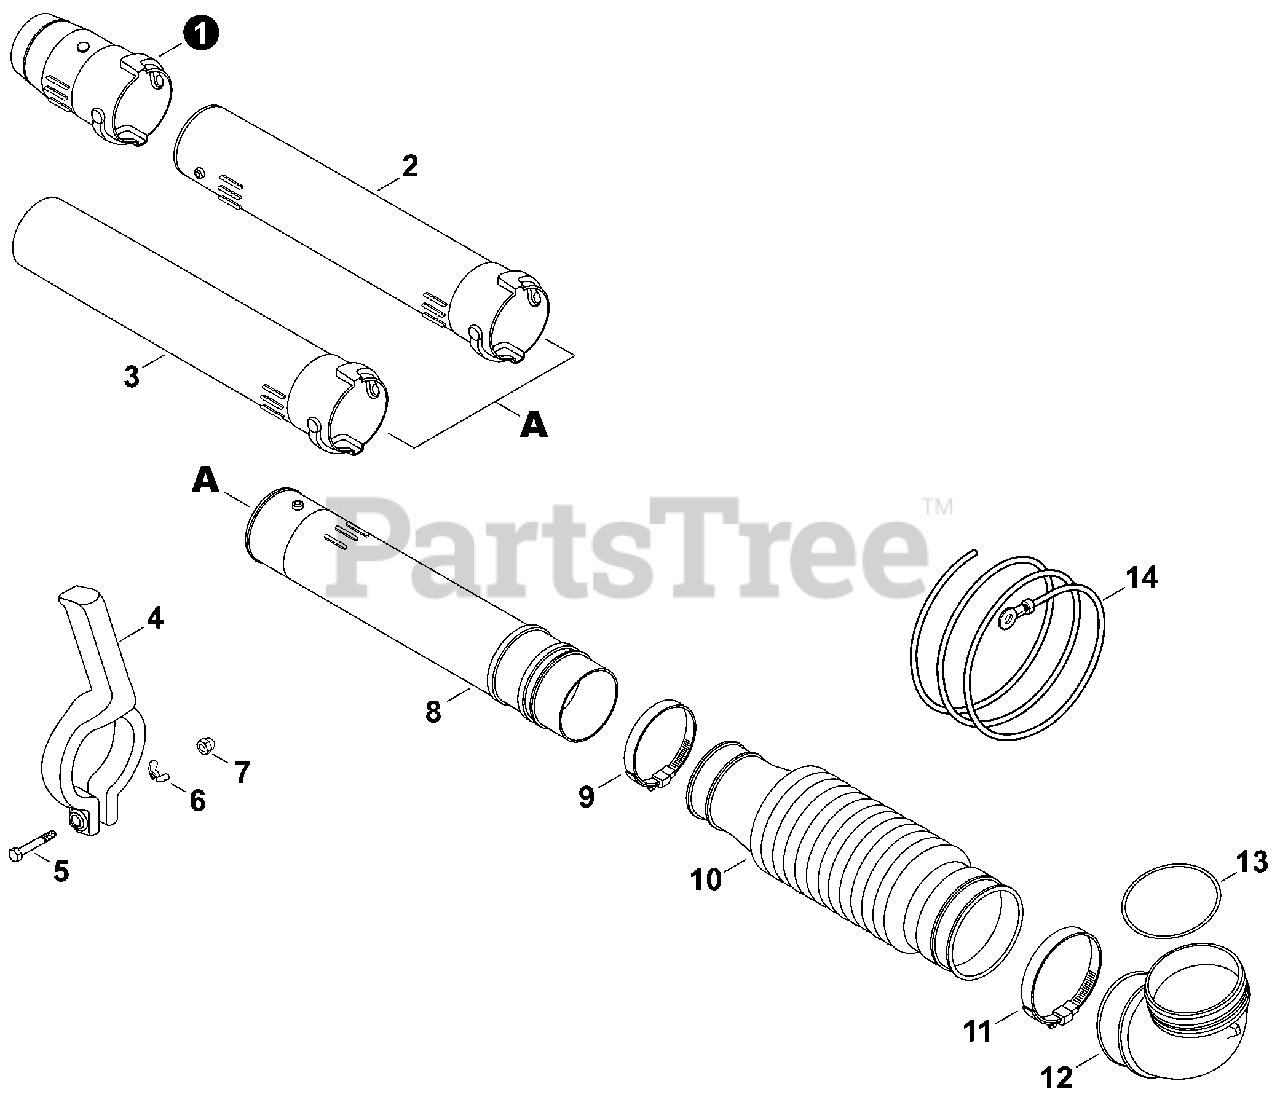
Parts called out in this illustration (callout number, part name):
1	TUBE, BLOWER - NOZZLE
2	TUBE, BLOWER - STRAIGHT
3	TUBE, BLOWER - NOZZLE
5	BOLT M6×60
6	NUT, WING M7
8	TUBE, BLOWER - SWIVEL
10	TUBE, BLOWER - FLEXIBLE
12	TUBE, BLOWER - ELBOW
14	WIRE, STATIC DISCHARGE
